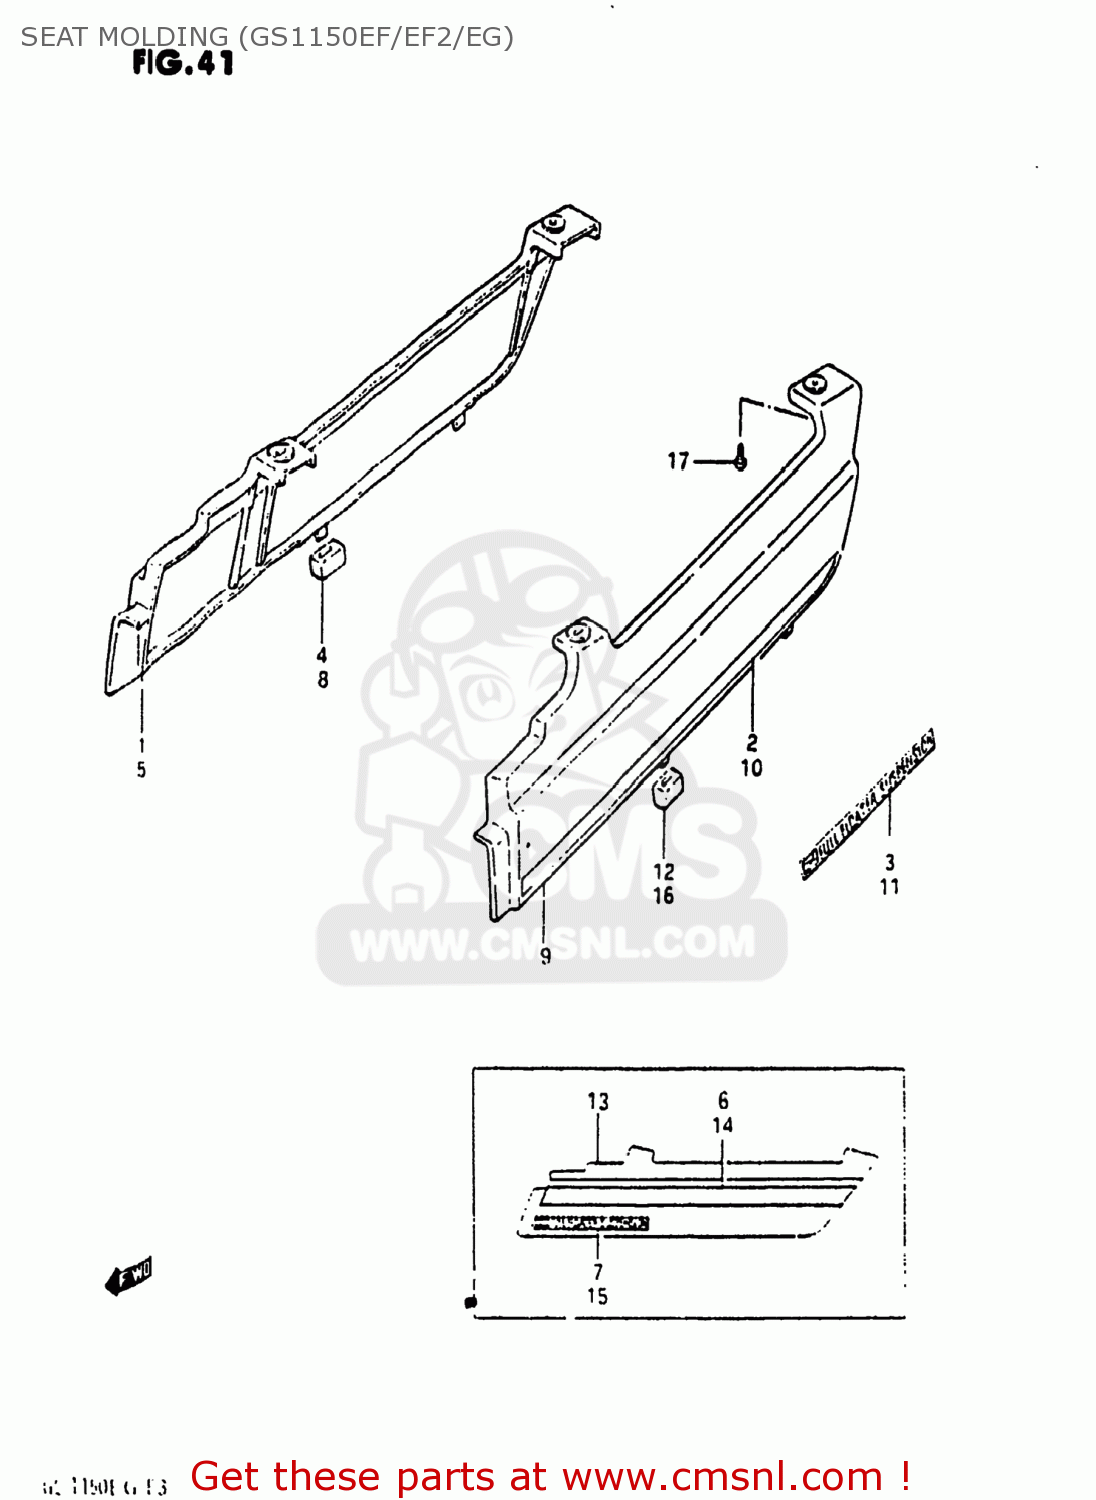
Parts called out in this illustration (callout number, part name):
1	MOLDING,SEAT,RIGHT
2	TAPE SET,SEAT MOULDING
3	EMBLEM
4	CAP,SEAT,MOLDING
5	MOLDING,SEAT,RIGHT
6	TAPE SET,SEAT MOULDING
7	EMBLEM
8	CAP,SEAT,MOLDING
9	MOLDING,SEAT,LEFT
10	TAPE SET
11	EMBLEM
12	CAP,SEAT,MOLDING
13	MOLDING,SEAT,LEFT
14	TAPE SET
15	EMBLEM
16	CAP,SEAT,MOLDING
17	SCREW
